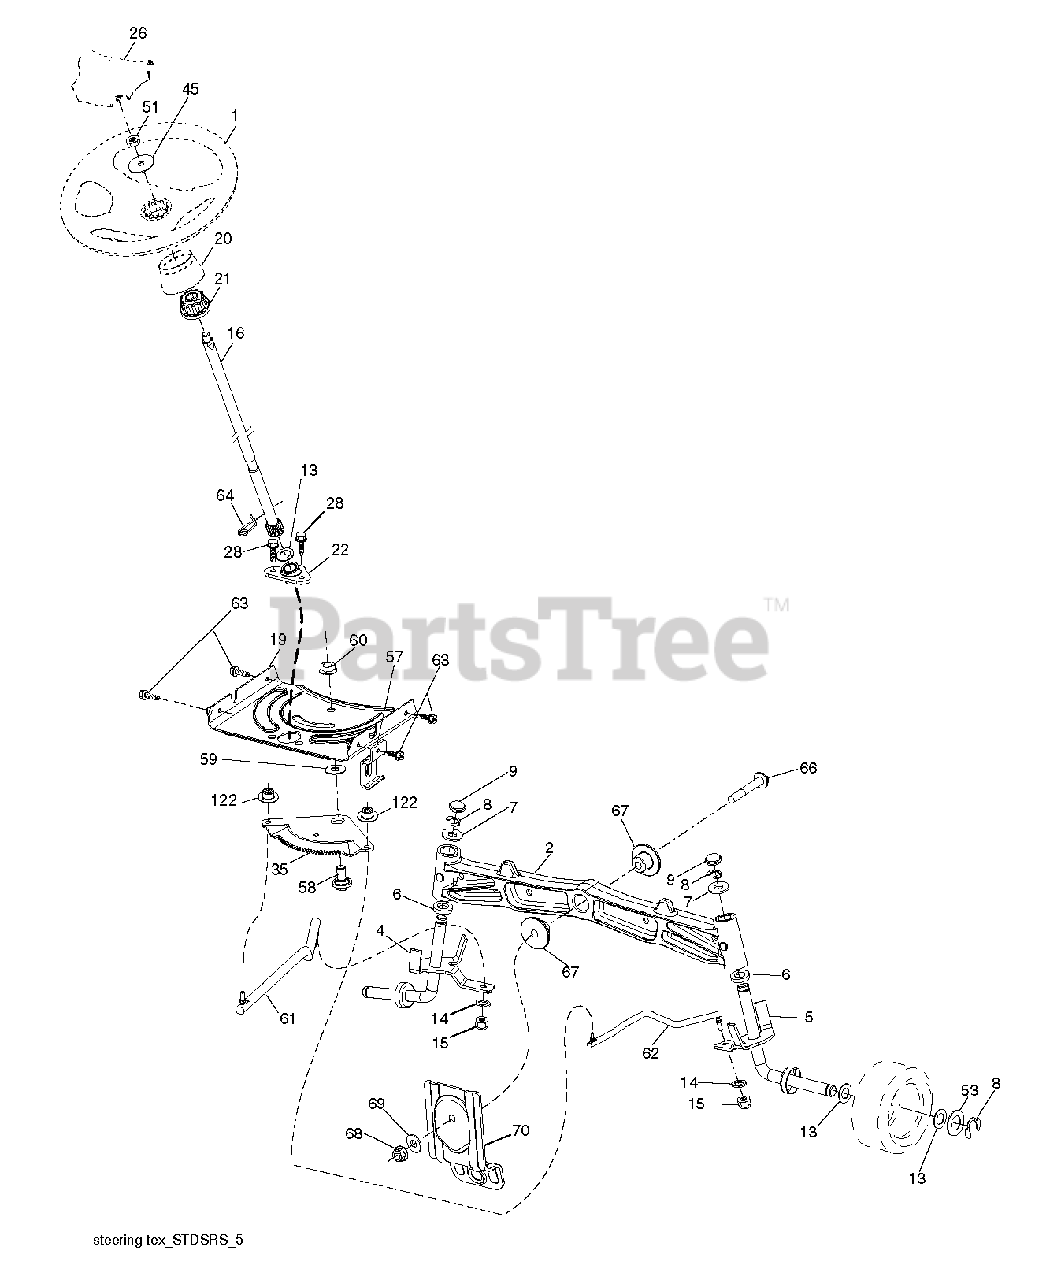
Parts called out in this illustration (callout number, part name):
1	WHEEL.STEERING.MLT.BR.YEL/OVRM
2	AXLE.CAST.IRON
4	SPINDLE.WELDED.LH.15"TEX
5	SPINDLE.WELDED.RH.15"T
8	RING CLIP
9	CAP.SPINDLE.BLACK
14	WASHER, LOCK 3/8
15	NUT CROWNLOCK 3/8-24
16	SHAFT, STEERING
19	PLATE.STEER.DDL.NLT/NG
20	CAP.WHL.STRNG.MULTI.BRND.YEL
21	ADAPTER, WHEEL STNG..
22	STEERING.SUPT.LOWER.
26	CAP.WHL.STRNG.MULTI.BRND.YEL
28	SCREW, 3/8-16X3/4
35	GEAR.SECTOR.PLATE.DDL.
45	WASHER 9/16"ID, 2 3/8""OD
51	NUT.HEX.1/2-20
53	WASHER.HARDENED
57	BRKT.UPSTOP.GT/LT.TEX
58	BOLT.SHOULDER.SECTOR.P
59	WASHER.THURST.SECTOR.S
60	NUT FLANGE LOCK 5/8-11
61	DRAGLINK.LH.BALLSTUD.D
62	DRAGLINK.RH.BALLSTUD.D
63	SCREW
64	RETAINER.CLIP.SPRING.S
66	BOLT HEX FGHD 7/16-14 X 3 SERR
67	BUSHING.PM.FRONT AXLE
68	NUT.LOCK.FLANGE.7/16
69	WASHER.1.5X.505X.118
70	BRKT.DECK.SUSPENSION.F
122	CAP.GEAR.SECTOR.TEX
